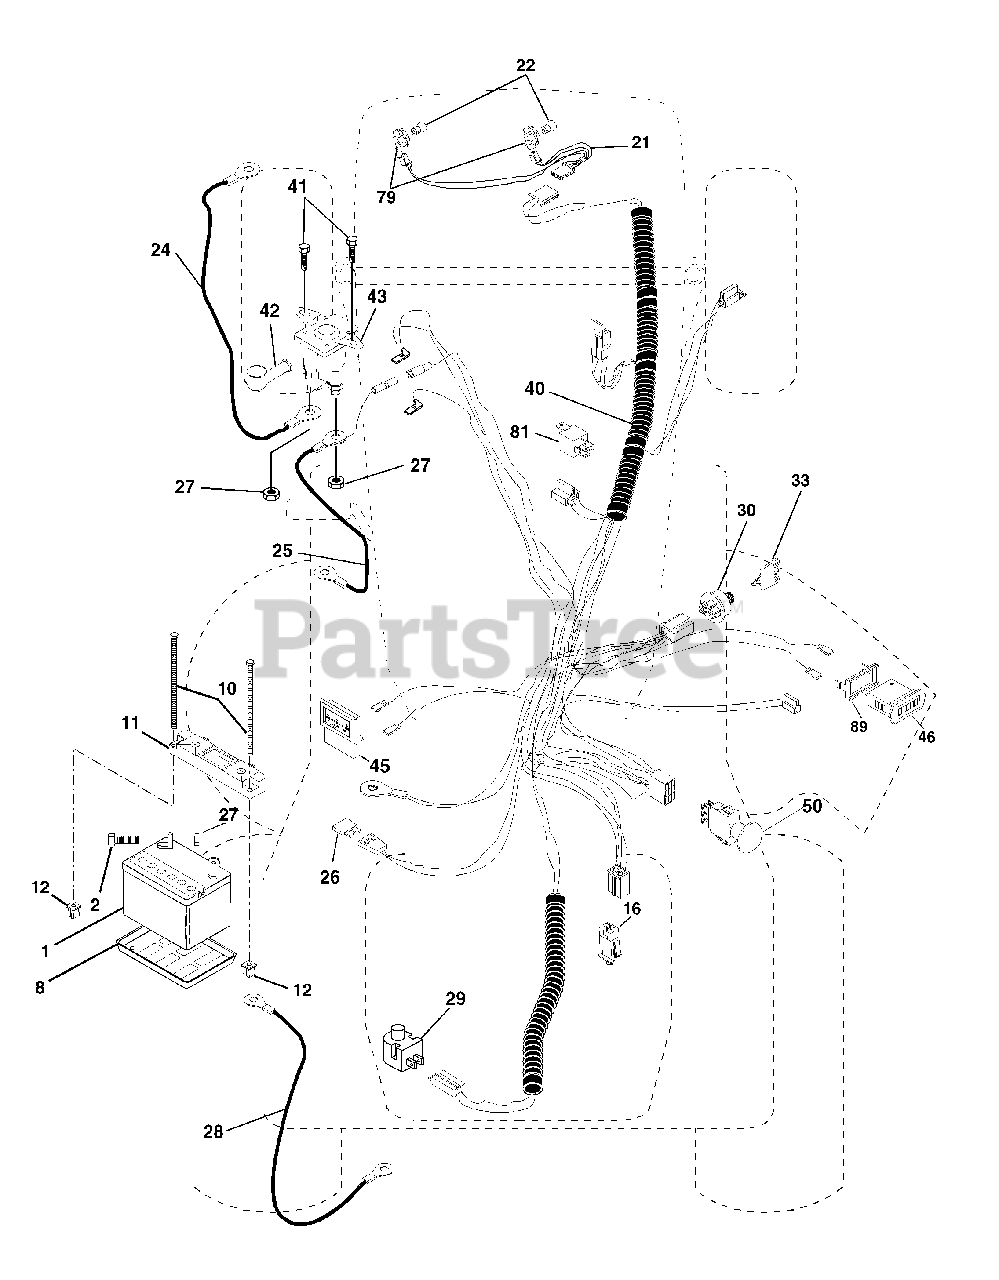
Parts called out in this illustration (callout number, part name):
1	Battery
2	Bolt Hex Head 1/4-20 x 3/4
8	Tray, Battery
10	Bolt, Battery Front 1/4-20 x 7.5 Zinc
11	Holddown Battery Front Mount
12	Nut, Push Nylon 1.4" Battery Front
16	Switch Interlock Push-In
21	Harness Socket Light w/4152J
22	Bulb Light
24	Cable, Battery
25	Cable, Battery
27	Nut Keps Hex 1/4-20
28	Cable, Ground
29	Switch, Plunger Normal Op Olive
30	Switch, Ign
40	Harness Ign.
41	Screw 1/4-20 x 1/2
42	Cover, Terminal Red
43	Solenoid
46	Hourmeter Snap-In
50	Switch, PTO
79	Bulbholder Asm
81	Relay Asm.
89	Bracket Snap-In Hourmeter
